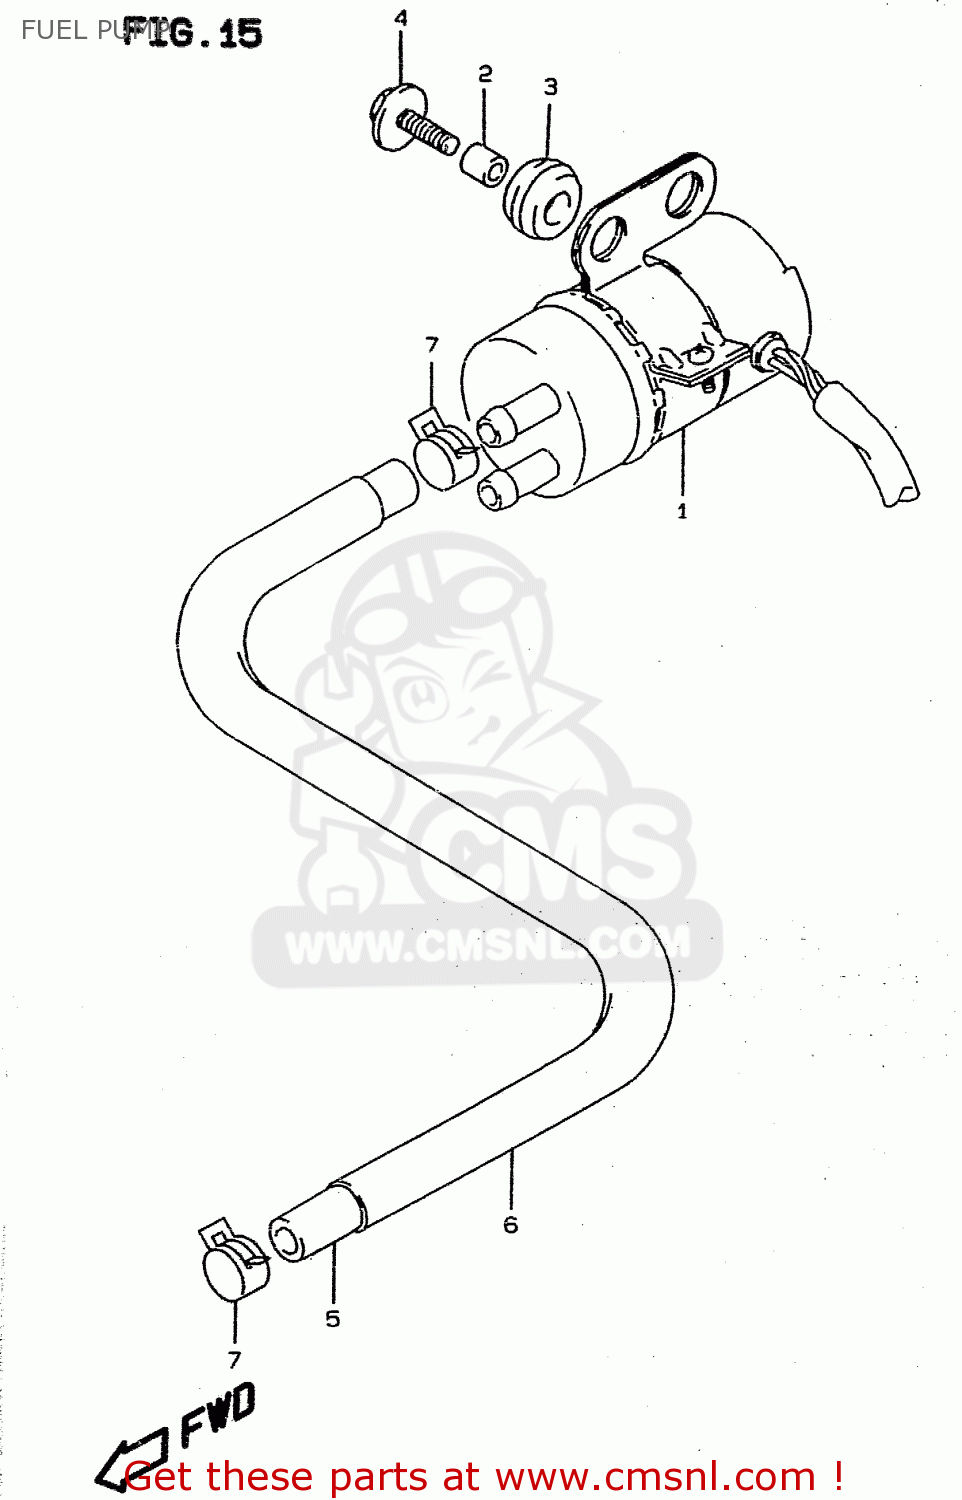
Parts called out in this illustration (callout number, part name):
1	PUMP ASSY,FUEL
2	SPACER(6.5X9X9)
3	CUSHION
4	BOLT(6X20)
5	HOSE(7X12X600)
6	PROTECTOR(14.5X15.5X600)
7	CLIP
